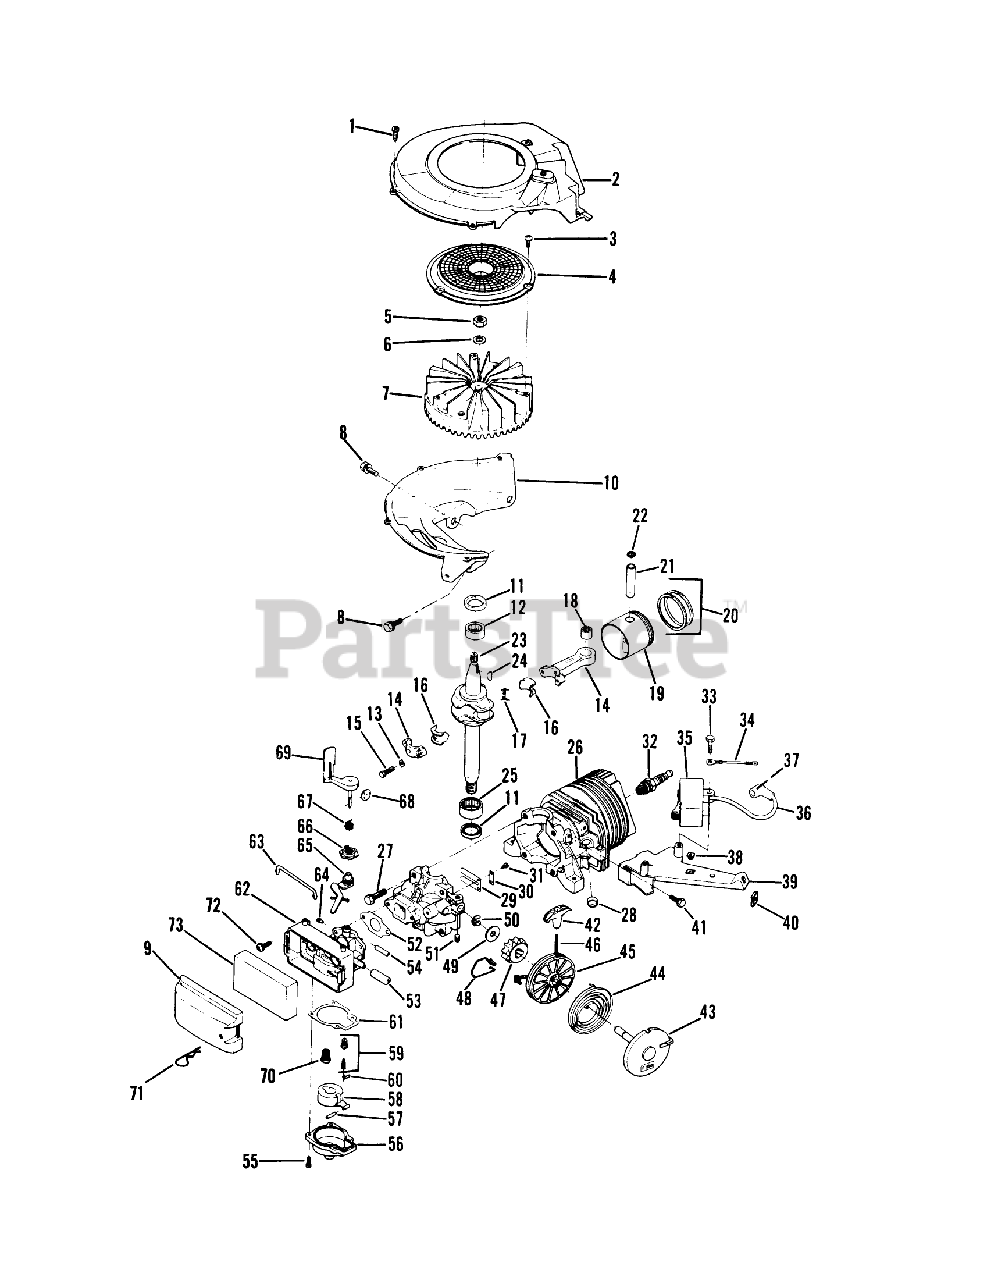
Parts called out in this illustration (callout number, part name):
1	SCREW S
2	AIR BAF&EYELET S
3	SCREW F
5	NUT
8	SCREW-SEMS
12	BEARING V
15	SCREW
16	LINER ASM
18	BEARING AY F
22	RING-RETAINING
24	KEY
25	BEARING V
27	SCREW S
28	PLUG-CORE VF
30	PLATE-BACKUP, REED
36	HT LEAD&COVER XEV
38	NUT-CLIP
40	NUT - SPEED S
42	HANDLE STARTER S
44	SPRING S
48	SPRING F
49	WASHER S
51	SET SCREW
52	GASKET CARB S
54	TUBING PRIMER S
55	SCREW-HH
62	Carburetor Body
63	RETAINER
64	F-SCREW CARB
65	LEVER
66	ADJUSTMENT COLLAR
67	SPRING
68	DISC S
71	HAIR PIN
72	SCREW
